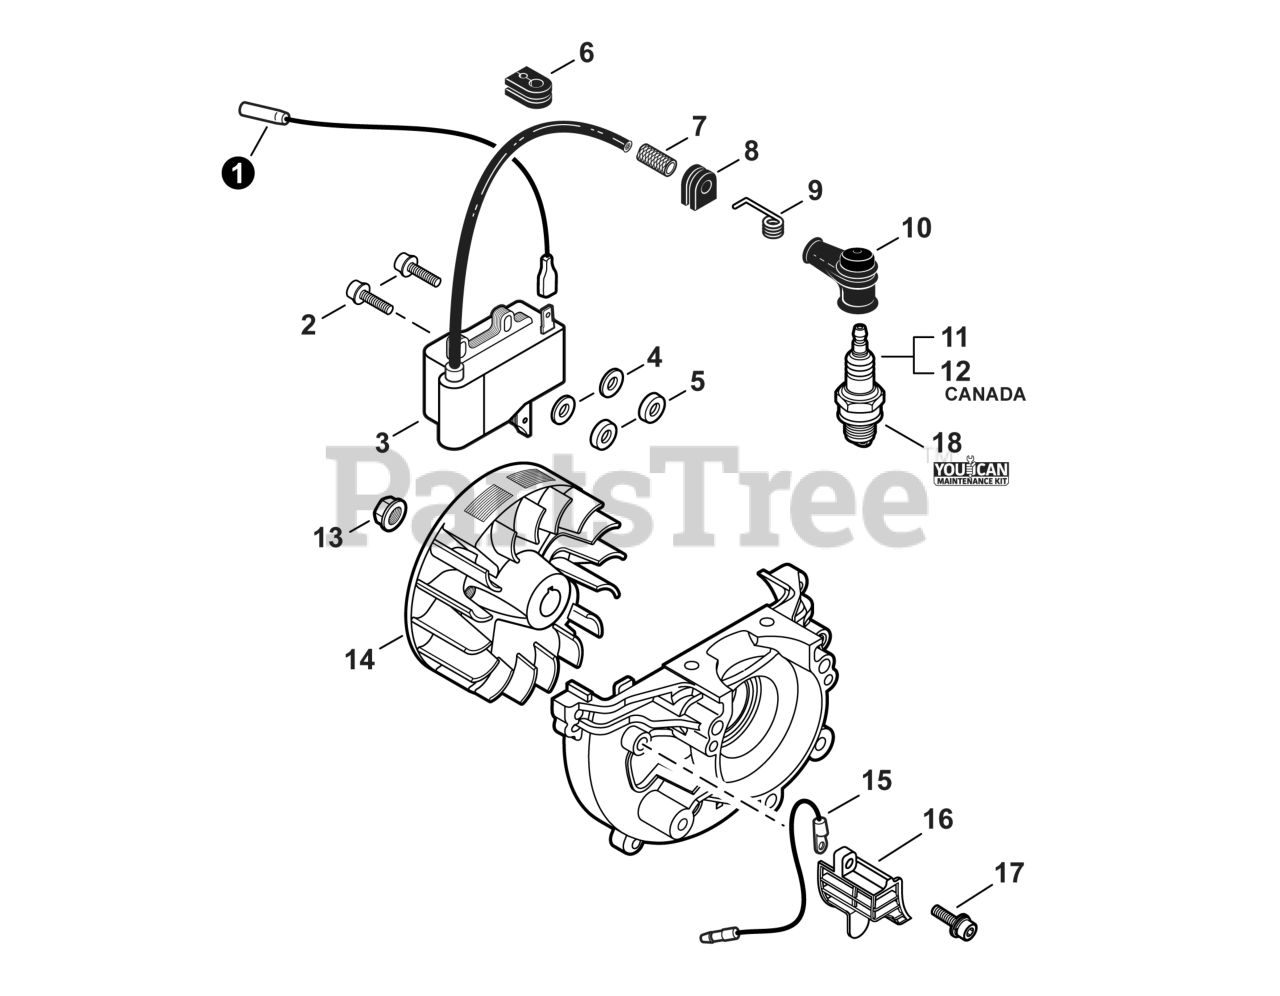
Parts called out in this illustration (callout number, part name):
1	LEAD - IGNITION
3	COIL, IGNITION
4	WASHER 4 MM
5	INSULATOR 4
6	GROMMET
7	TUBE, INSULATOR
9	TERMINAL, SPARK PLUG
10	CAP, SPARK PLUG
11	SPARK PLUG - BPM8Y
12	SPARK PLUG - BPMR8Y
13	NUT, FLANGE M8
14	FLYWHEEL
15	LEAD - GROUND
16	COVER, DUST
17	BOLT 5x16
18	TUNE-UP KIT - YOUCANT
